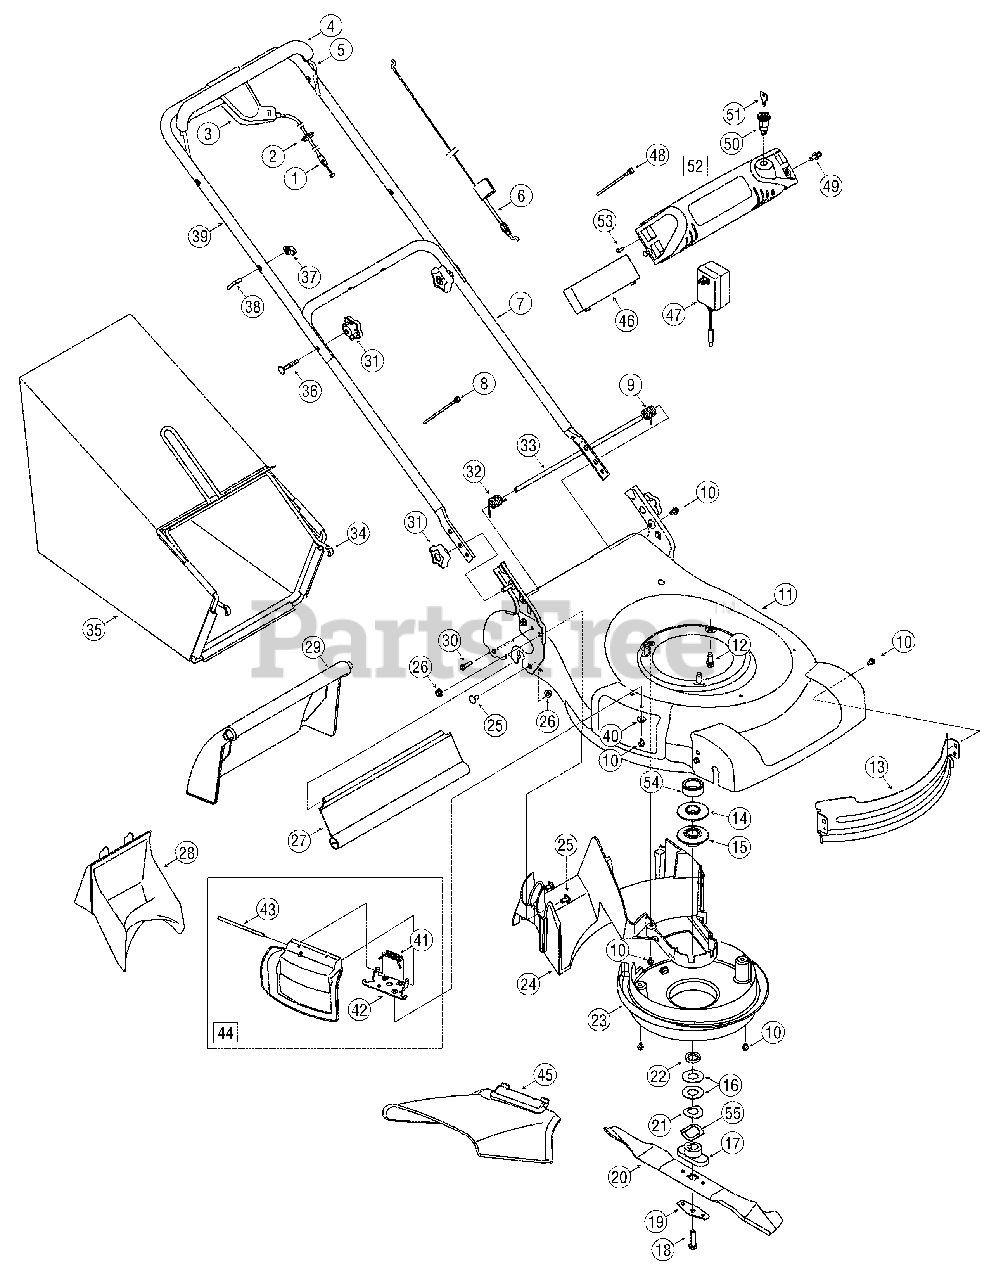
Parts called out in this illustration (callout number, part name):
1	Drive Cable
2	Rubber Grommet
3	Drive Control Assembly
4	Bail Cover
6	Control Cable
8	Cable Tie
9	Torsion Spring, LH
10	TT Screw, 1/4-20 x .62
12	TT Screw, 3/8-16 x 1.00
13	Front Deck Baffle
14	Upper Engine Pulley
15	Lower Engine Pulley
16	Flat Wash., .885 x 1.850 x .060
17	Blade Adapter
18	Screw, 3/8-24 x 1.50
19	Blade Bell Support
20	21" Mulching Blade
21	Sprg Washer, .890 x 1.70 x .048
22	Sleeve Spacer, .88 x 1.13 x .12
22	Slv. Spcr., 25mm x 1.375 x .375
23	Engine Baffle
24	Deck Baffle
25	Carriage Bolt, 5/16-18 x .62
25	Hex Cap Screw, 5/16-18 x .625 GR5
26	Flange Lock Nut, 5/16-18
27	Trailshield
28	Mulch Plug
29	Rear Door
30	Screw, 1/4-15 x 1.00
31	Star Knob
32	Torsion Spring, RH
33	Door Pivot Rod
36	Carriage Bolt, 5/16-18 x 2.00
41	Torsion Spring
42	Chute Deflector Adapter
43	Hinge Pin
44	Mulch Plug Assembly
45	Side Discharge Chute
46	12 Volt Battery
47	Battery Charger
48	Cable Tie
49	Rivet
50	Key Switch
51	Key
52	Electric Starter Harness Ass'y.
53	Screw, #10-16 x .750
54	Sleeve Spacer
55	Washer, Wave, 1.5 x 1.0 x .029
